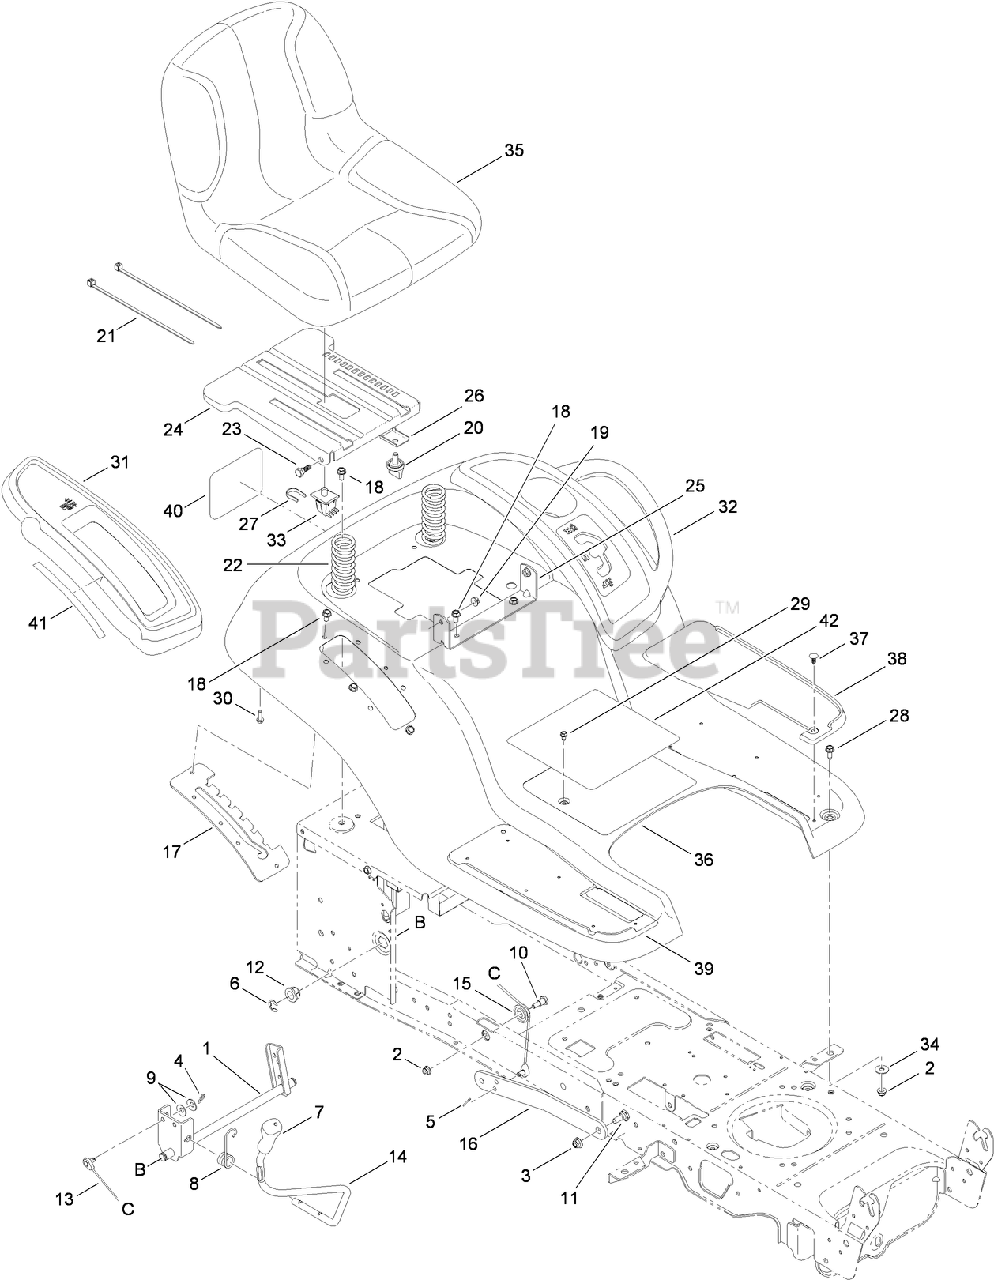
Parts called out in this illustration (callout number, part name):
1	LIFT SHAFT ASM
2	NUT-LOCK, FLANGE
3	NUT-LOCK, FLANGE
4	PIN-COTTER
5	PIN-COTTER
6	RING-E
7	GRIP-HANDLE
8	SPRING-TORSION
9	WASHER-SPRING
10	BOLT-SHOULDER
11	BOLT-SHOULDER
12	BEARING-FLANGE
13	CABLE-LIFT
14	HANDLE-LIFT
15	PULLEY-CABLE
16	ARM-LIFT
17	BRACKET-LIFT
18	SCREW-TAP
19	NUT-LOCK, FLANGE
21	TIE-CABLE
22	SPRING-COMPRESSION
23	BOLT-SHOULDER
24	BRACKET-MOUNT, SEAT
25	BRACKET-PIVOT, SEAT
26	BRACKET-KNOB, ADJUSTMENT
27	CLIP-RETENSION
28	SCREW-HH
29	SCREW-HWHTF
30	SCREW-TAP
31	COVER-FENDER, RH
32	COVER-FENDER, LH (W/CUPHOLDER)
33	SWITCH-SEAT
34	WASHER-FLAT
35	SEAT-HIGH
36	FENDER
37	CLIP-RATCHET
38	PAD-FOOT, LH
39	PAD-FOOT, RH
40	DECAL-TORO
41	DECAL-HOC
42	DECAL-SAFETY
